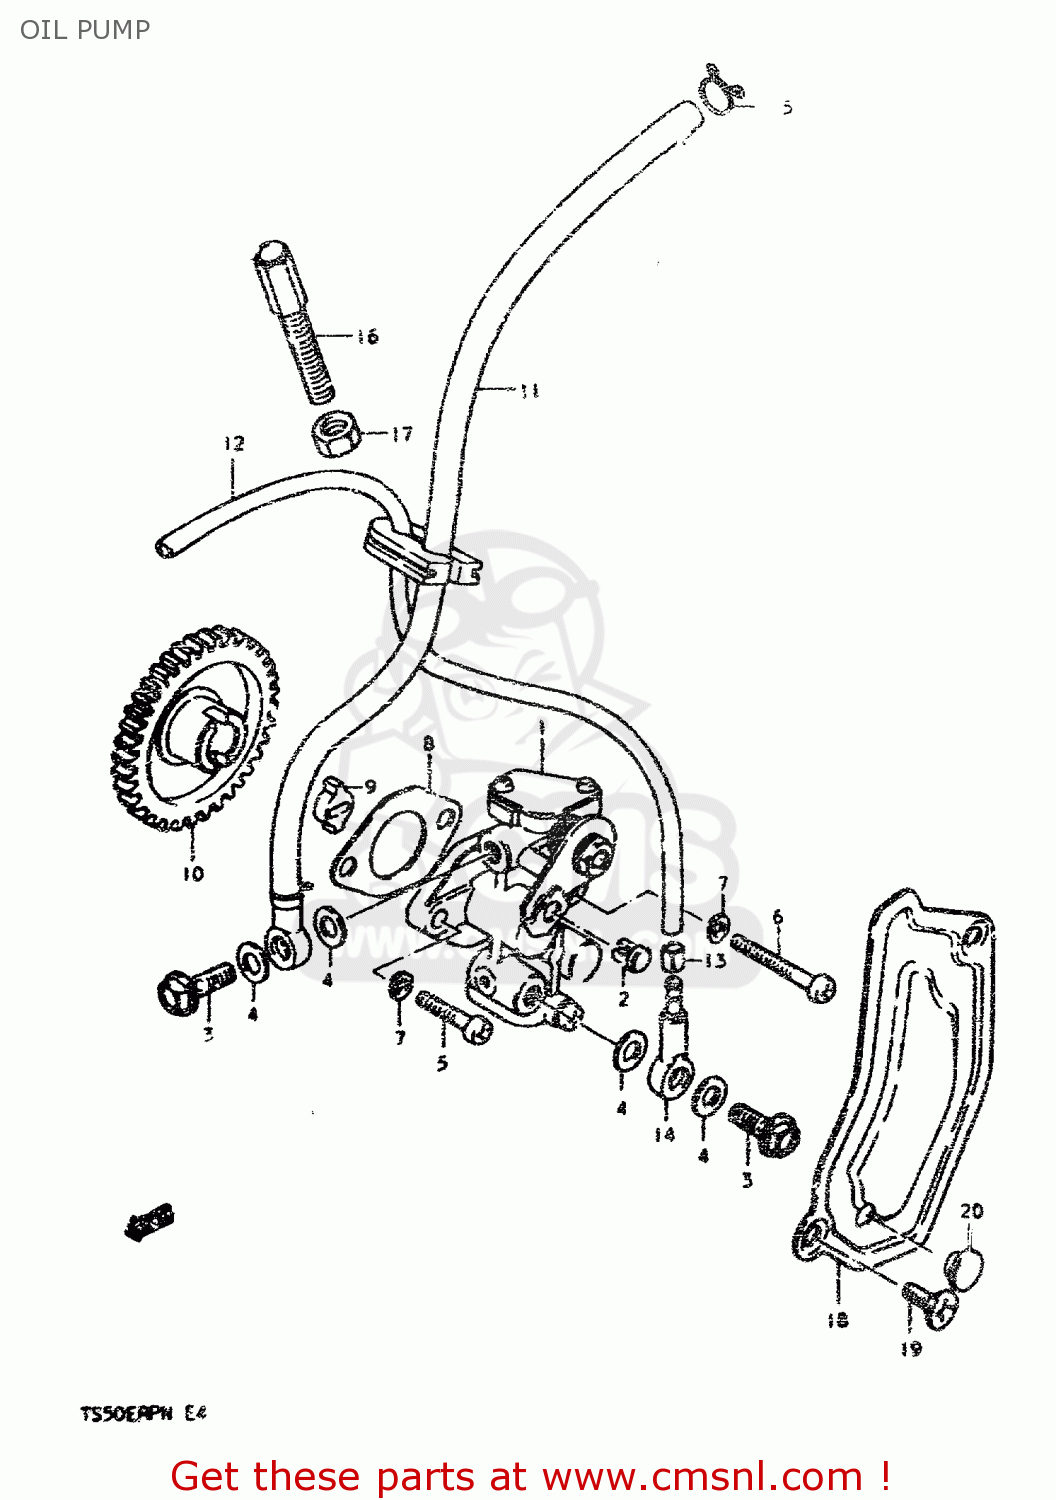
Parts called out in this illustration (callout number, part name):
1	PUMP ASSEMBLY,OIL
2	TERMINAL,CABLE
3	UNION BOLT
4	GASKET(6.2X11X1).2 (NAS)
5	SCREW
6	SCREW
7	LOCK WASHER
8	GASKET,OIL PUMP (NAS)
9	PIECE,OIL PUMP DRIVE
10	GEAR,OIL PUMP DRIVE
11	HOSE, OIL INLET
12	HOSE,OIL
13	CLIP
14	VALVE,CHECK
15	CLIP
16	BOLT
17	NUT
18	CAP, INSPECTION
19	SCREW
20	CUSHION
